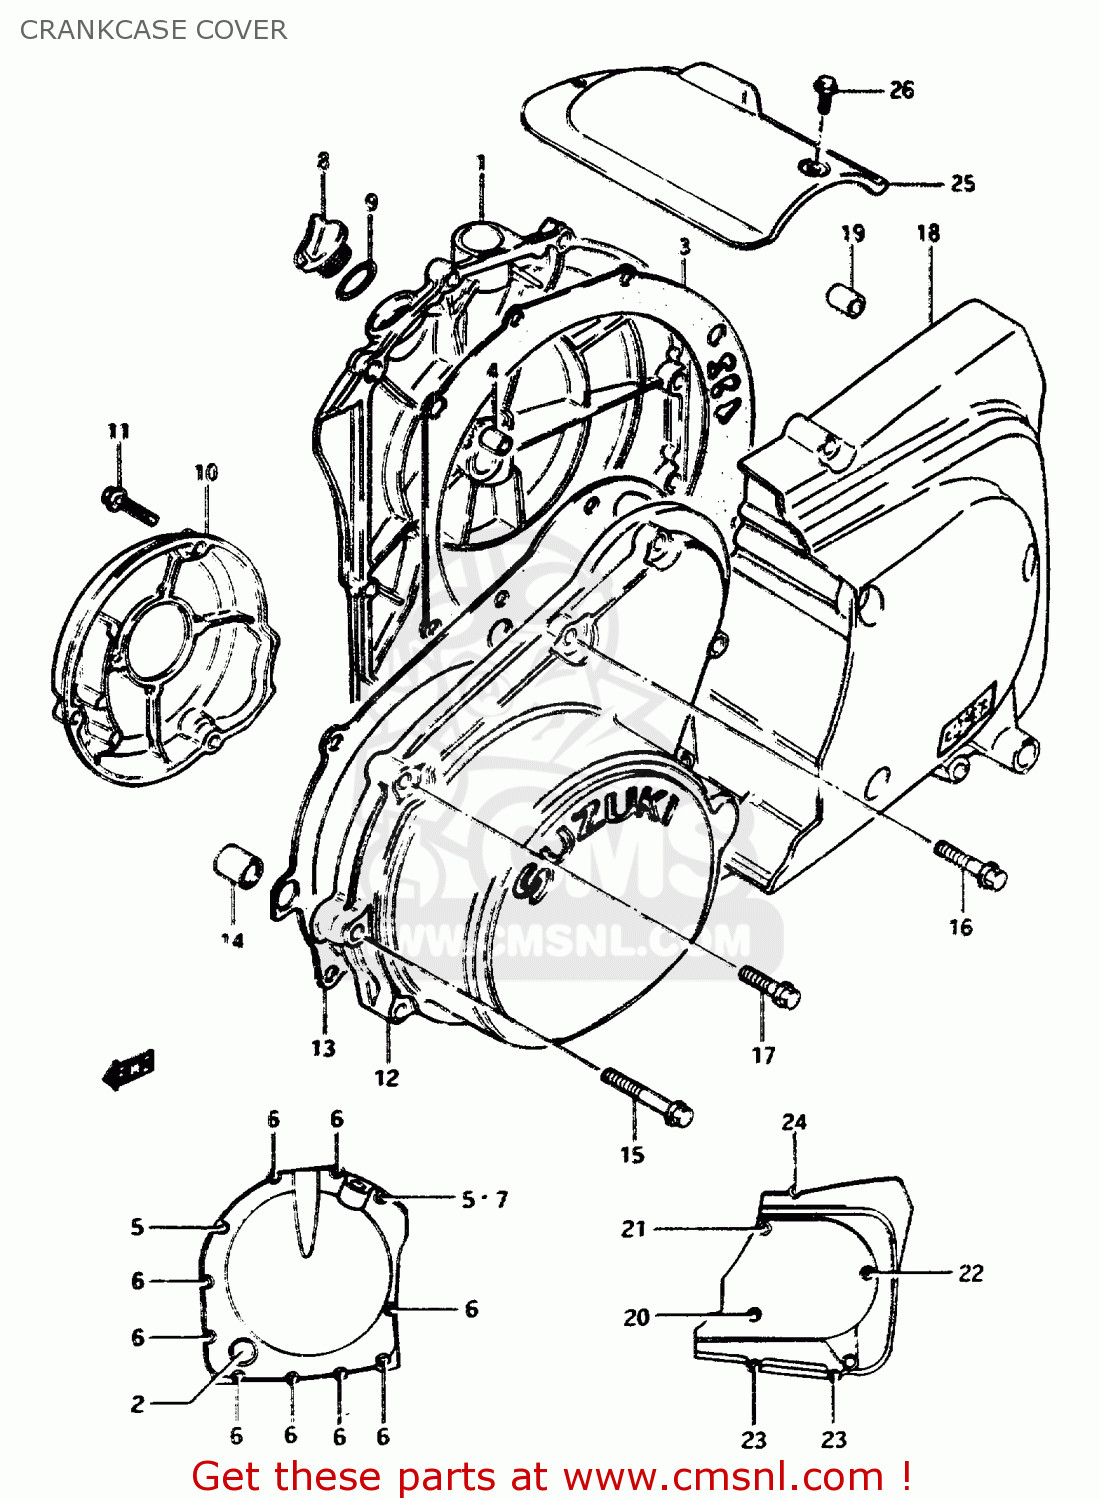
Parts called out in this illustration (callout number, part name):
1	COVER,CLUTCH
2	LENS,OIL LEVEL CHECK
3	GASKET,CLUTCH COVER (MCA)
4	PIN
5	BOLT
6	BOLT
7	WASHER
8	PLUG
9	O RING(D:3.1,ID:16.8)
10	COVER,CONTACT BREAKER
11	BOLT
12	COVER,MAGNETO
13	GASKET,MAGNETO COVER (MCA)
14	PIN
15	BOLT
16	BOLT
17	BOLT
18	COVER,ENGINE SPROCKET
19	PIN
20	BOLT
21	BOLT
22	BOLT
23	BOLT
24	BOLT
25	COVER,STARTER MOTOR
26	BOLT
